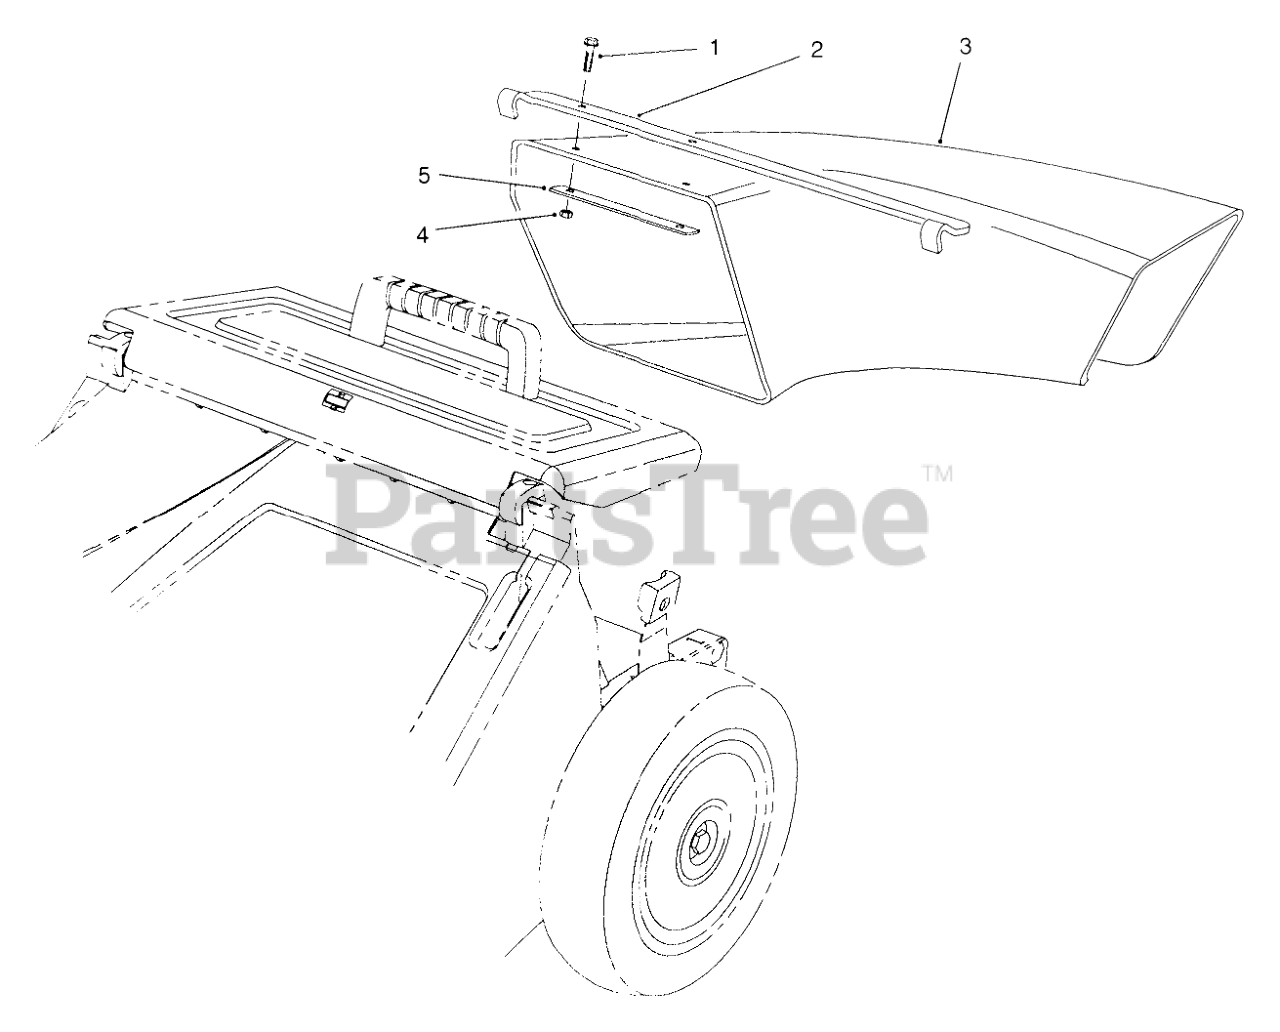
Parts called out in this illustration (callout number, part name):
1	SCREW-HWH
2	CHUTE HANGER BRACKET
3	Chute-Discharge
4	NUT-LOCK, NI
5	STRESS PLATE
